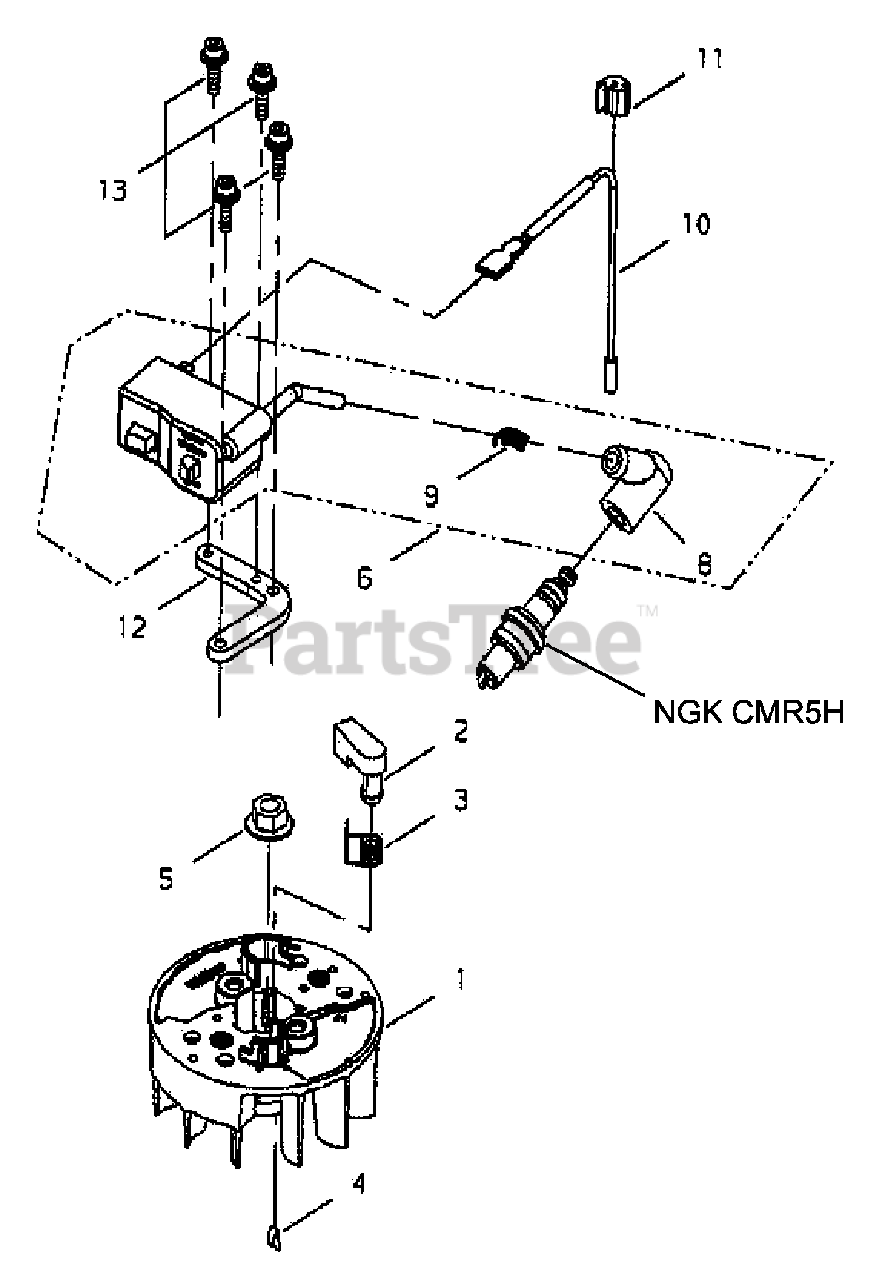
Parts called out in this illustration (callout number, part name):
1	FLYWHEEL
2	PAWL, STARTER
3	SPRING
4	KEY - 3X10
5	NUT - 8
6	IGNITION COIL ASSY
8	CAP, SPARK PLUG
9	TERMINAL, SPARK PLUG CAP
10	LEAD - IGNITION
11	GROMMET
12	STAY
13	SCREW - 4X16
